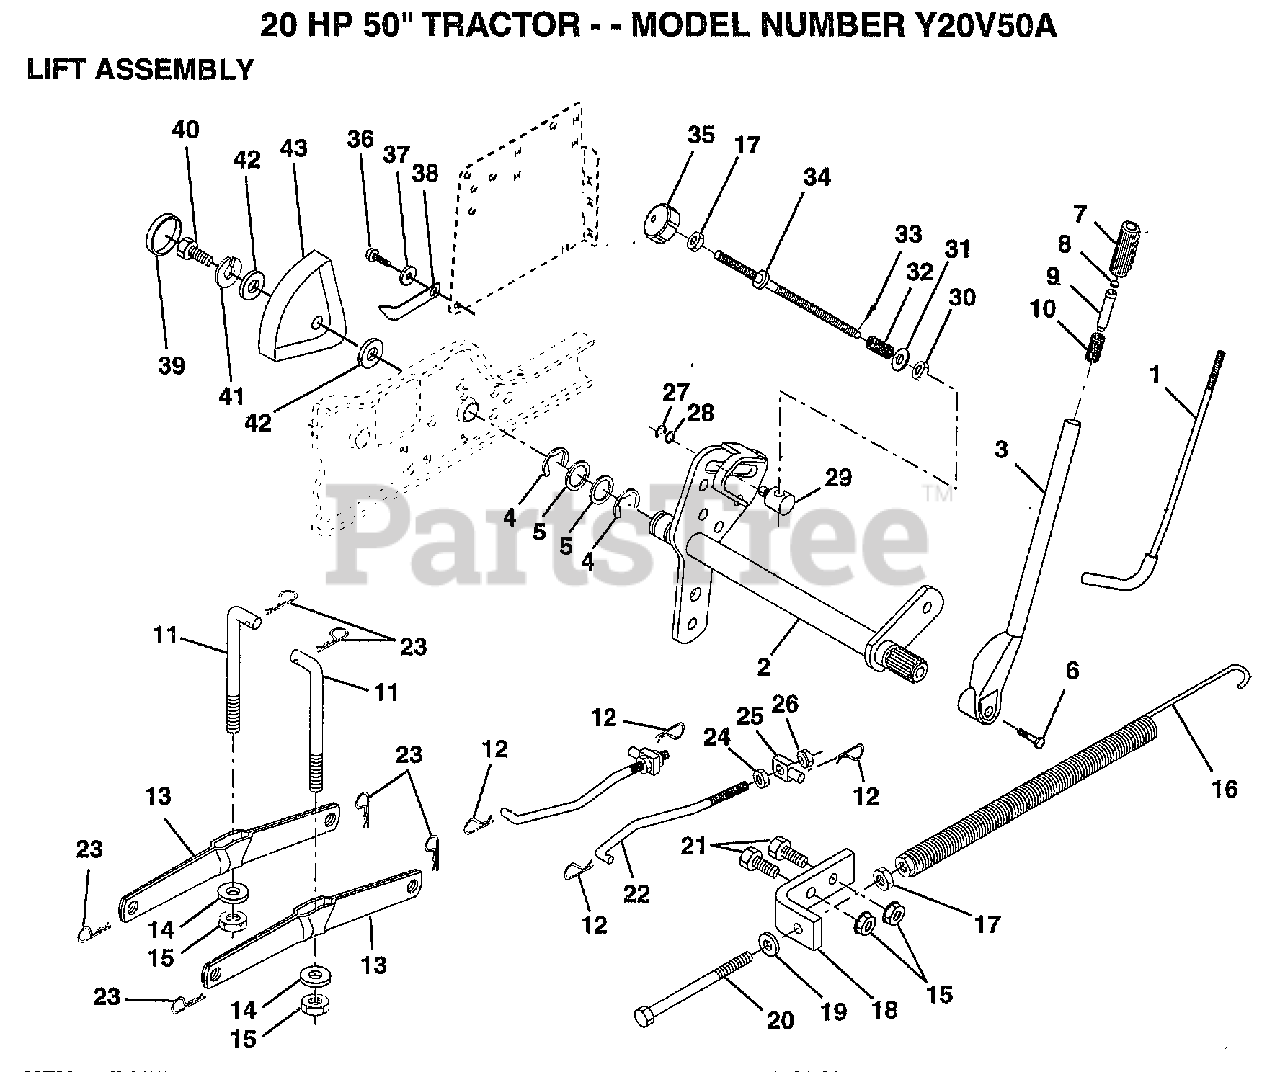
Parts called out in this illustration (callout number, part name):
1	LEVER ROD LT
4	E-RING
5	WASHER
6	"BOLT,HEX"
7	GRIP HANDLE
10	SPRING T
12	RETAINER.SPRING
14	BEARING PVT LH
15	NUT
17	NUT
18	BRACKET SPRING AS
19	WASHER
20	BOLT-ADJ SPRING T
21	BOLT
22	LINK.FRONT
24	NUT
25	TRUNION
26	NUT.LK.W/WSH.1/2.
27	KLIP RING
28	WASHER
29	TRUNION LT
30	NUT T
31	WASHER
32	SPRING.COMP.INF.H
34	ROD.ADJ.LIFT
35	KNOB INF 3/8-16
36	SCREW
37	WASHER T
38	POINTER HGT IND
39	"PLUG,HOLE"
40	SCREW TI
41	LOCKWASHER
42	WASHER
43	HEIGHT INDICATOR
